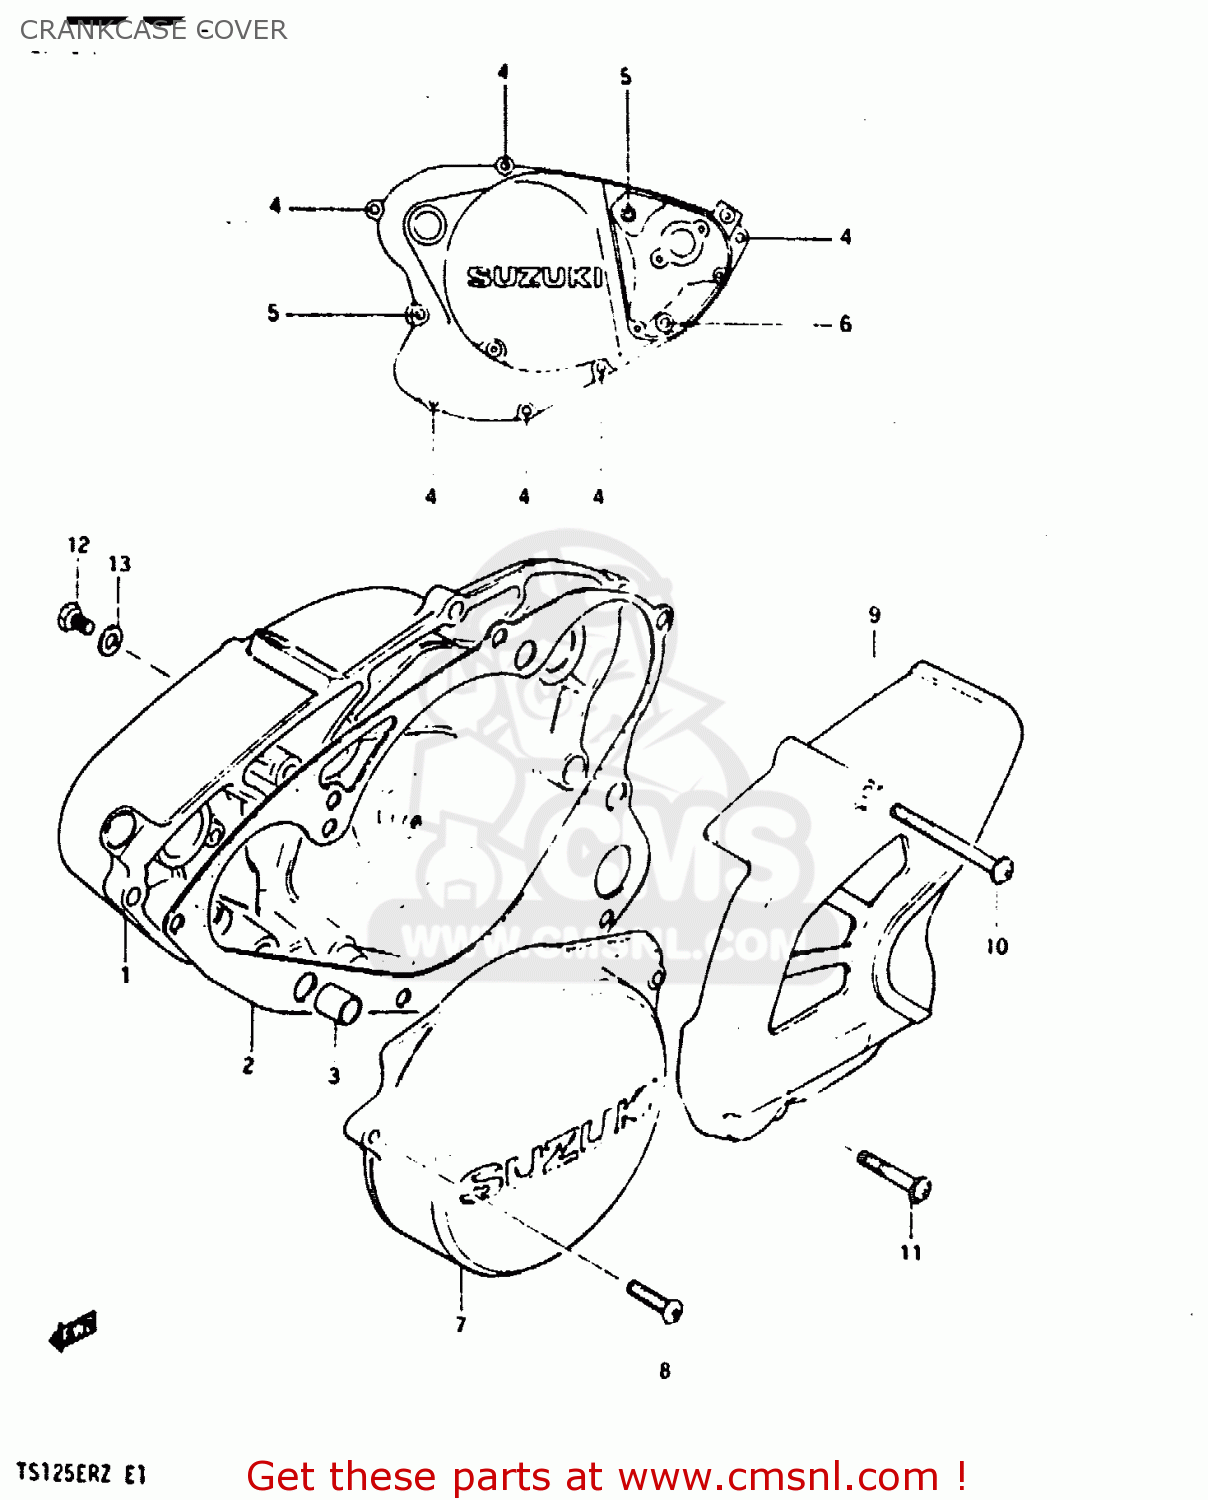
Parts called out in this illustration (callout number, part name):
1	COVER,CLUTCH
2	GASKET (MCA)
3	PIN
4	SCREW
5	SCREW
6	SCREW (6X45)
7	COVER,MAGNETO
8	SCREW 5X20
9	COVER,ENGINE SPROCKET
10	SCREW
11	SCREW
12	SCREW(6X10)
13	GASKET(6.2X11X1) (NAS)
